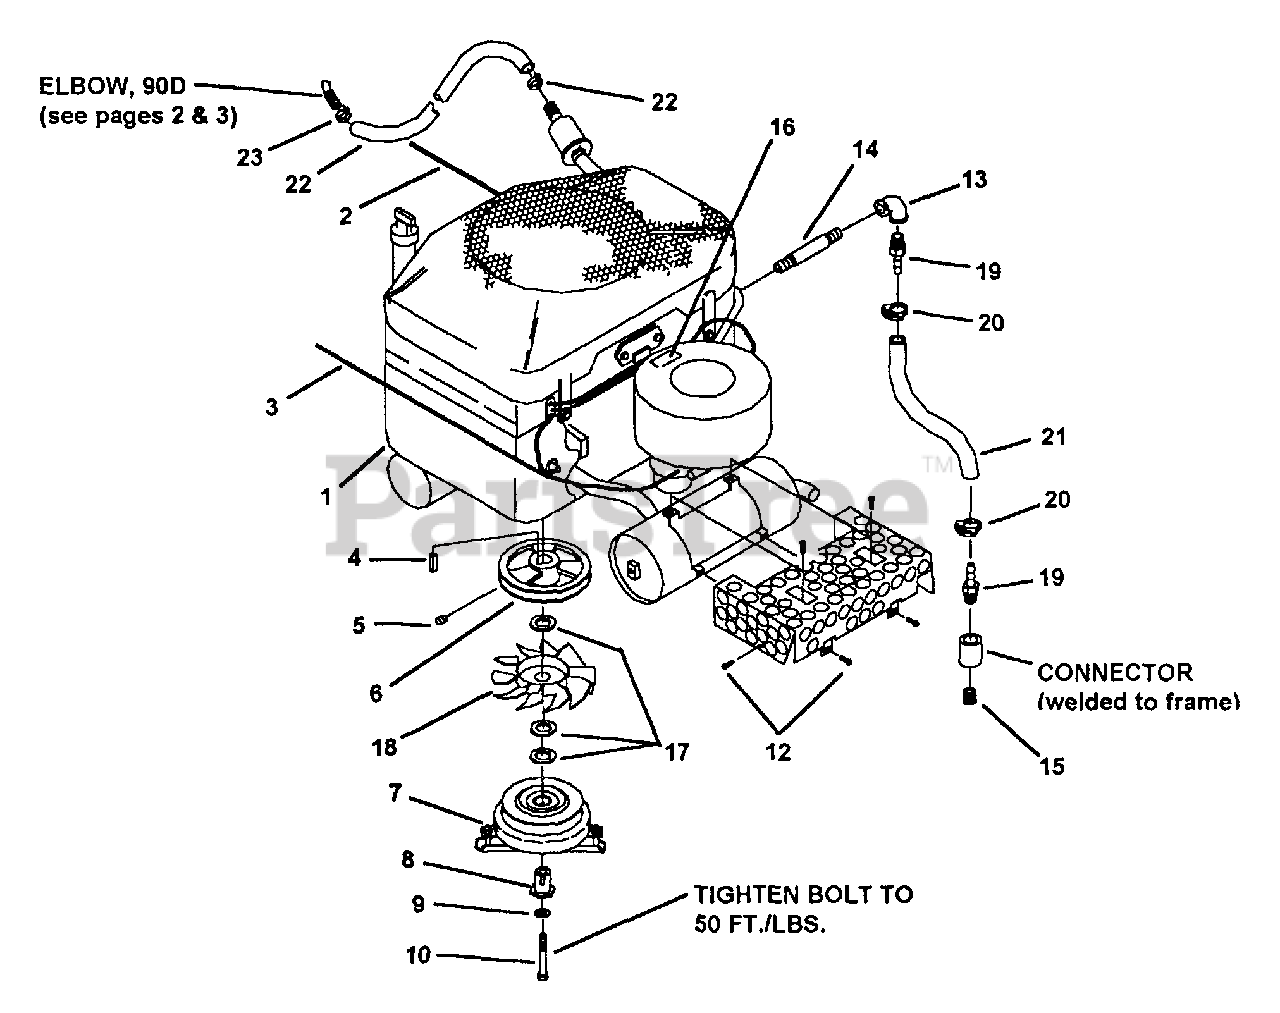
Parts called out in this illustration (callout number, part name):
1	* 18 HP KOHLER, VERTICAL SHAFT ENGINE
1	* 20 HP KOHLER, VERTICAL SHAFT ENGINE
2	CABLE, THROTTLE 18 & 20 HP
3	CABLE, CHOKE 18 & 20 HP
4	KEY, SQUARE, 1/4" X 1"
4	KEY, WOODRUFF, 1/4" X 3/4"
5	SETSCREW, SOCKET HD., 5/16-18 X 3/8"
6	PULLEY, 1" BORE
6	PULLEY, 1-1/8" BORE
7	CLUTCH, ELECTRIC, 1" BORE
8	BUSHING, CLUTCH
9	LOCKWASHER, 7/16" SPLIT SPRING
10	CAPSCREW, 7/16-20 X 3-1/4" GR. 5
12	SCREW, SHEET METAL, #8 X 1/2"
13	ELBOW, 3/8, 90D, SCH. 40 CAST IRON
14	NIPPLE, 3/8 X 3" SCH. 40 BLACK
15	PLUG, PIPE 3/8"
16	DECAL, "PERIODICALLY CLEAN"
17	WASHER, SHIM
18	FAN, 7" DIA. 10 BLADE CW
19	HOSE BARB, 3/8" HOSE X 3/8" NPT
20	HOSE CLAMP, 19-32-21/32, NYLON
21	HOSE, 3/8" ID X 6-3/4" LONG
22	FUEL LINE, 19"
23	CLAMP, HOSE SPRING TYPE 1/2" O.D.
